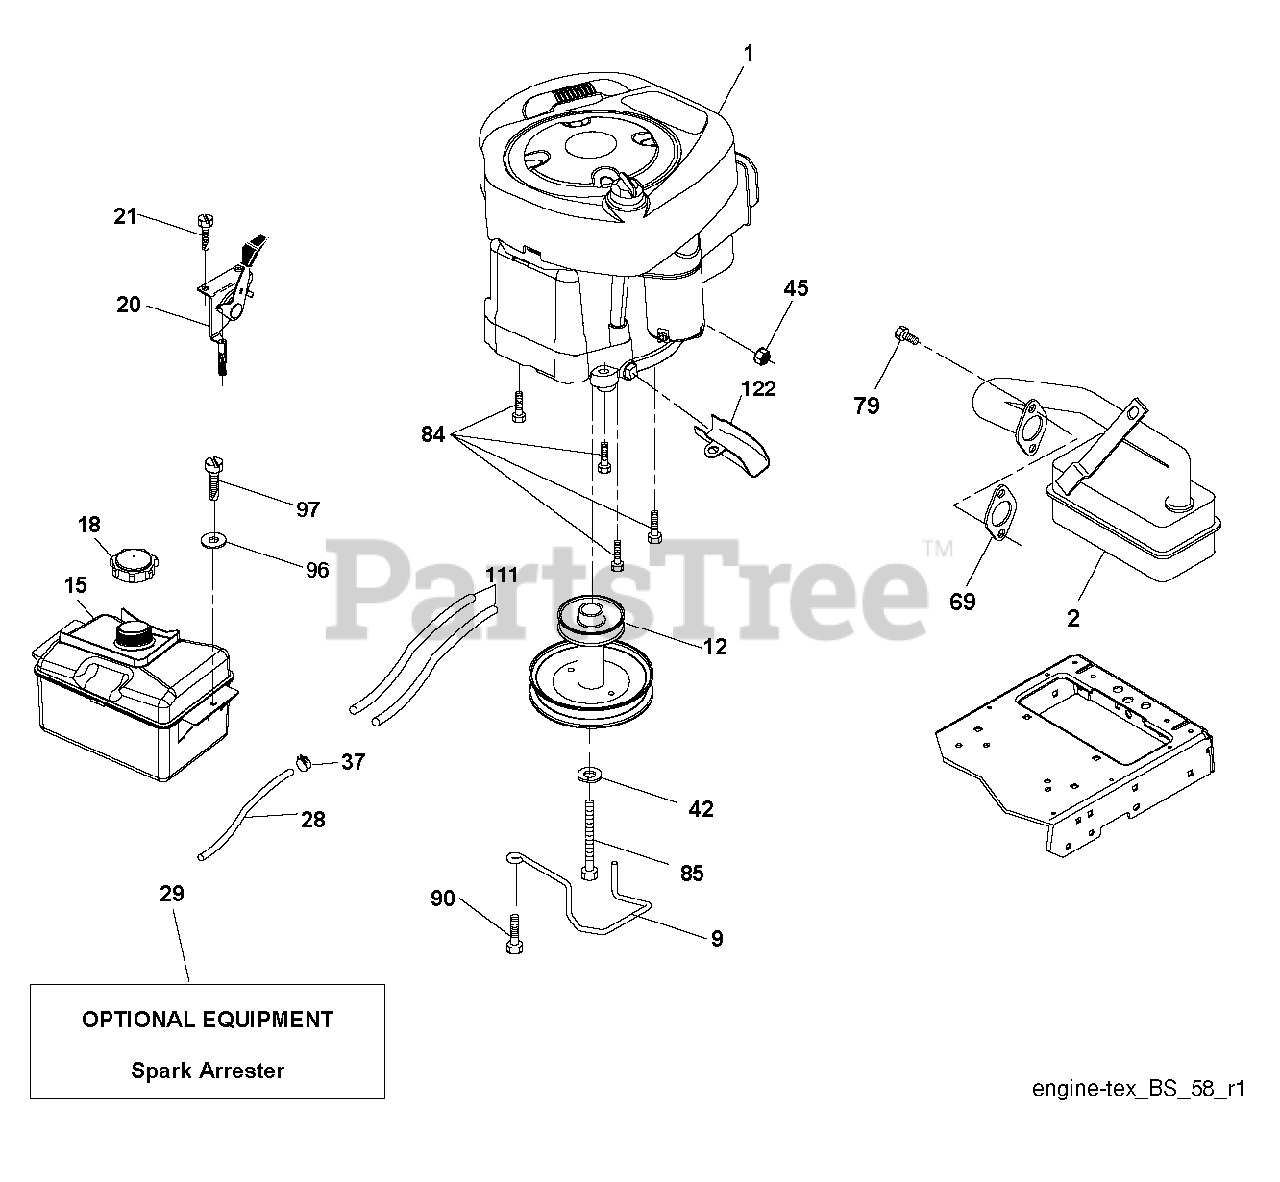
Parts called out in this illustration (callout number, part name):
2	MUFFLER.LT.BRIGGS.14HP.IC/OHV
9	KEEPER.BELT.ENGINE.3.25 (3 2)
12	PULLEY.ENG.CL.MECH.SLVR.LT/YT
15	TANK.ASM.1.5GAL.FRT.W/CAP.EPA
18	CAP.FUEL.2 WAY VENT
20	CONTROL.TH/CK.C.
21	SCREW.#10 X 0.750.BOS
28	LINE.FUEL.20"FRONT.EMI
29	KIT.SPARK ARRESTOR 794945 B&S
37	HOSE CLAMP
42	LOCKWASHER
45	NUT
69	REPL BY 532 27 22-93
79	SCREW.SOCKET HD.5/16-1
84	SCREW.3/8-16
85	BOLT HEX 7/16-20X4-1/4"
90	SCREW 3/8-16X1
97	SCREW HEXWSHR 1/4-20X3/4
111	RP PURGE LINE
122	EXTENSION DRAIN OIL
